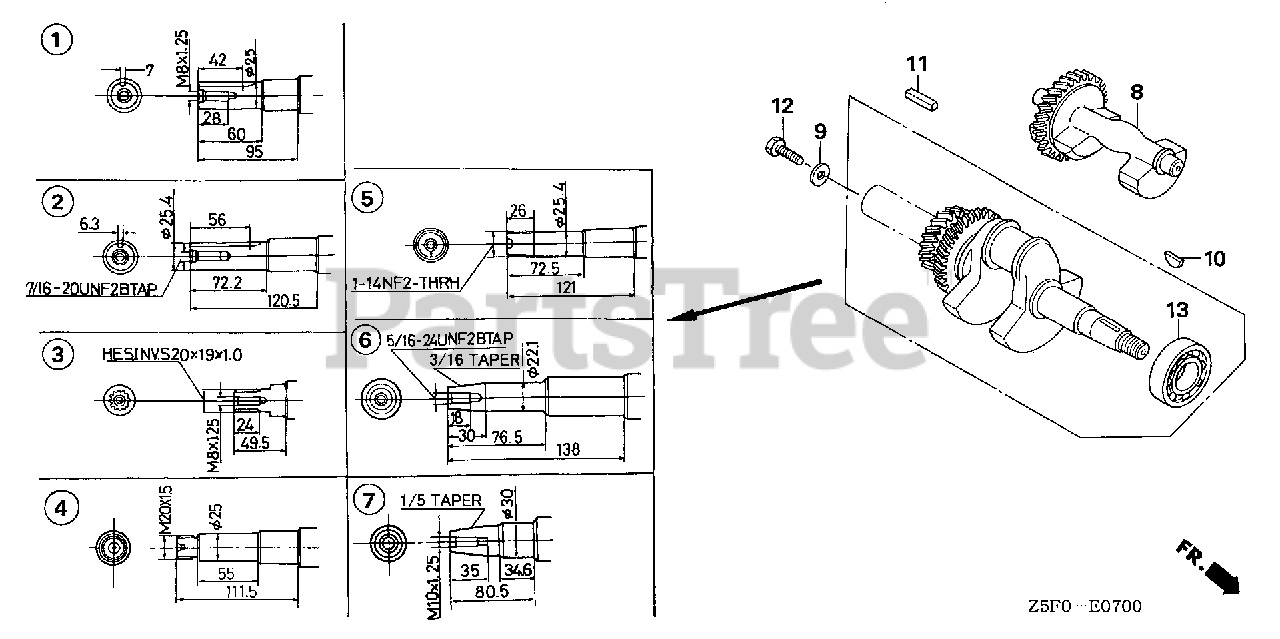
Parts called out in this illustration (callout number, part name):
6	CRANKSHAFT
8	WEIGHT, BALANCER
10	KEY, SPECIAL WOODRUFF (25X18)
13	BEARING, RADIAL BALL (6206)
